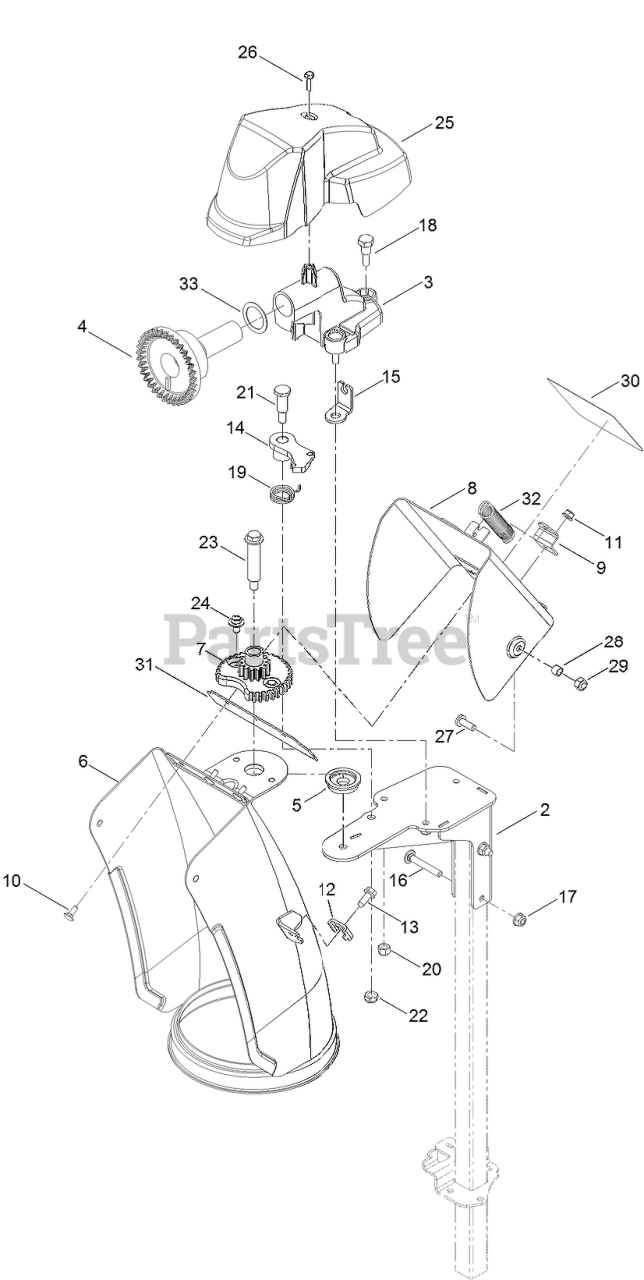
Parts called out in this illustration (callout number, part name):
2	SUPPORT-CHUTE
3	MOUNT-GEAR, FACE
4	GEAR-FACE
5	SPACER-CHUTE
6	CHUTE WELD ASM
7	GEAR-CHUTE
8	DEFLECTOR WELD ASM
9	BRACKET-SPRING
10	BOLT-CARR
11	NUT-HF
12	CLAMP-CABLE
13	SCREW-HWH
14	LATCH-CHUTE
15	ANCHOR-CABLE
16	BOLT-CARR
17	NUT-FLANGE, NI
18	SCREW-SHOULDER
19	SPRING-TORSION
20	NUT-HEX
21	SCREW-SHOULDER, HH
22	NUT-HEX
23	BOLT-SHOULDER
24	SCREW AND WASHER ASM
25	COVER-CHUTE, GEAR
26	SCREW-HWH
27	SCREW-PH
28	SPACER
29	NUT-HEX
30	DECAL-DANGER
31	GASKET-DEFLECTOR
32	SPRING-CHUTE, UPPER
33	WASHER
